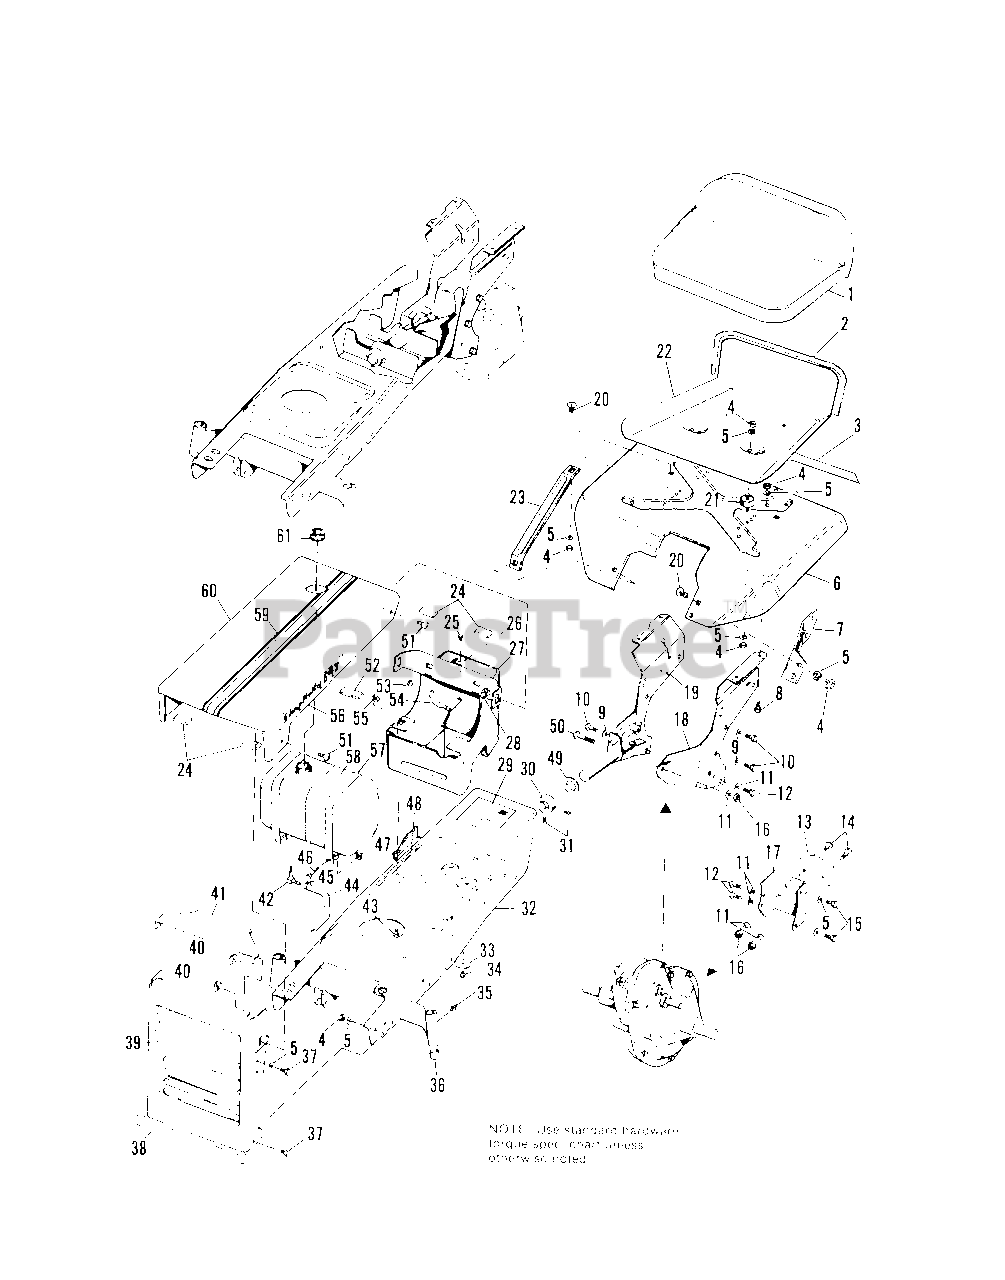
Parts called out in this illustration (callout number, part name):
1	PAD, Seat
2	TAPE, Seat Pan, 2 Feet
3	EMBLEM, Rear
3	EMBLEM, Rear (990597 & 990598 Only)
4	NUT, Hex, Full, 5/16-18 (Qty. 14 on 990597, 990598, 990645 & 990646 Only)
5	LOCKWASHER, 5/16 (Qty. 18 on 990597, 990598, 990656 & 990646 Only)
6	SUPPORT, Seat
7	BRACKET (990778, 990779 & 990905 Only)
8	CAPSCREW, Hex Hd., 5/16-18 x 3/4
9	LOCKWASHER, 7/16
10	CAPSCREW, Hex Hd., 7/16-14 x 1
11	LOCKWASHER, 3/8
12	CAPSCREW, Hex Hd., 3/8-16 x 3/4
13	CLIP, Draw Bar
14	CAPSCREW, Hex Hd., 3/8-16 x 1
15	CAPSCREW, Hex Hd., 5/16-18 x 1-1/4
16	NUT, Hex, Full, 3/8-16
17	BRACKET, Draw Bar
18	PLATE, Side, L.H. (990778, 990779 & 990905 Only)
18	PLATE, Side, L.H.
19	PLATE ASSY., Side, R.H. (990778, 990779 & 990905 Only)
19	PLATE ASSY., Side, R.H.
20	BOLT, Carriage, 5/16-18 x 1/2
21	CONNECTOR, Cushion
22	PANEL, Seat
23	BRACE, Seat Support
23	DECAL, Safety
24	GASKET, Felt
25	SCREW, Self Tapping, Hex Hd., 1/4-20 x 1/2
26	DECAL, Throttle (990778, 990779 & 990905 Only)
26	DECAL, Throttle
27	DASH ASSY. (990778, 990779 & 990905 Only)
27	DASH ASSY.
28	NUT, Retainer
29	DECAL, Safety (990905 Only)
29	DECAL, Safety (990778 & 990779 Only)
30	COLLAR, Set
31	SETSCREW, 5/16-18 x 1/2
32	FRAME ASSY. (990905 Only)
32	FRAME ASSY.
33	WASHER, Plain, #10
34	FITTING, Grease
35	FITTING, Grease
36	BEARING, Needle
37	CAPSCREW, Hex Hd., 5/16-18 x 5/8
38	DECAL, Grille (990645, 990646, 990778, 990779 & 990905 Only)
38	GRILLE (990597 & 990598 Only)
39	GRILLE (990597 & 990598 Only)
40	NUT, Retainer
41	SUPPORT, Grille
42	ELBOW, 90ø (990778, 990779 & 990905 Only)
42	VALVE, Shutoff
43	SCREW, Self Tapping, Hex Hd., #14 x 5/8
44	HOSE, Fuel
45	CLAMP, Hose
46	SCREW, Machine, Fillister Hd., 1/4-20 x 1-3/4
47	NUT, Square, 1/4-20
48	DECAL, Clutch
50	CAPSCREW, Hex Hd., 3/8-16 x 1-3/4
50	CONTROL, Choke (990597 & 990598 Only)
51	SCREW, Thumb, 5/16-18 x 3/4
52	GASKET, Felt
53	BUTTON, Plug (990778, 990779 & 990905 Only)
54	CONTROL, Choke
55	NUT, Speed
56	DECAL, Number (990905 Only)
56	DECAL, Number
56	DECAL, Number (990597 & 990598 Only)
57	STRAP, Tank
58	TANK, Fuel
59	STRIPE, Hood
60	HOOD (990597 & 990598 Only)
61	CAP, Fuel Tank
